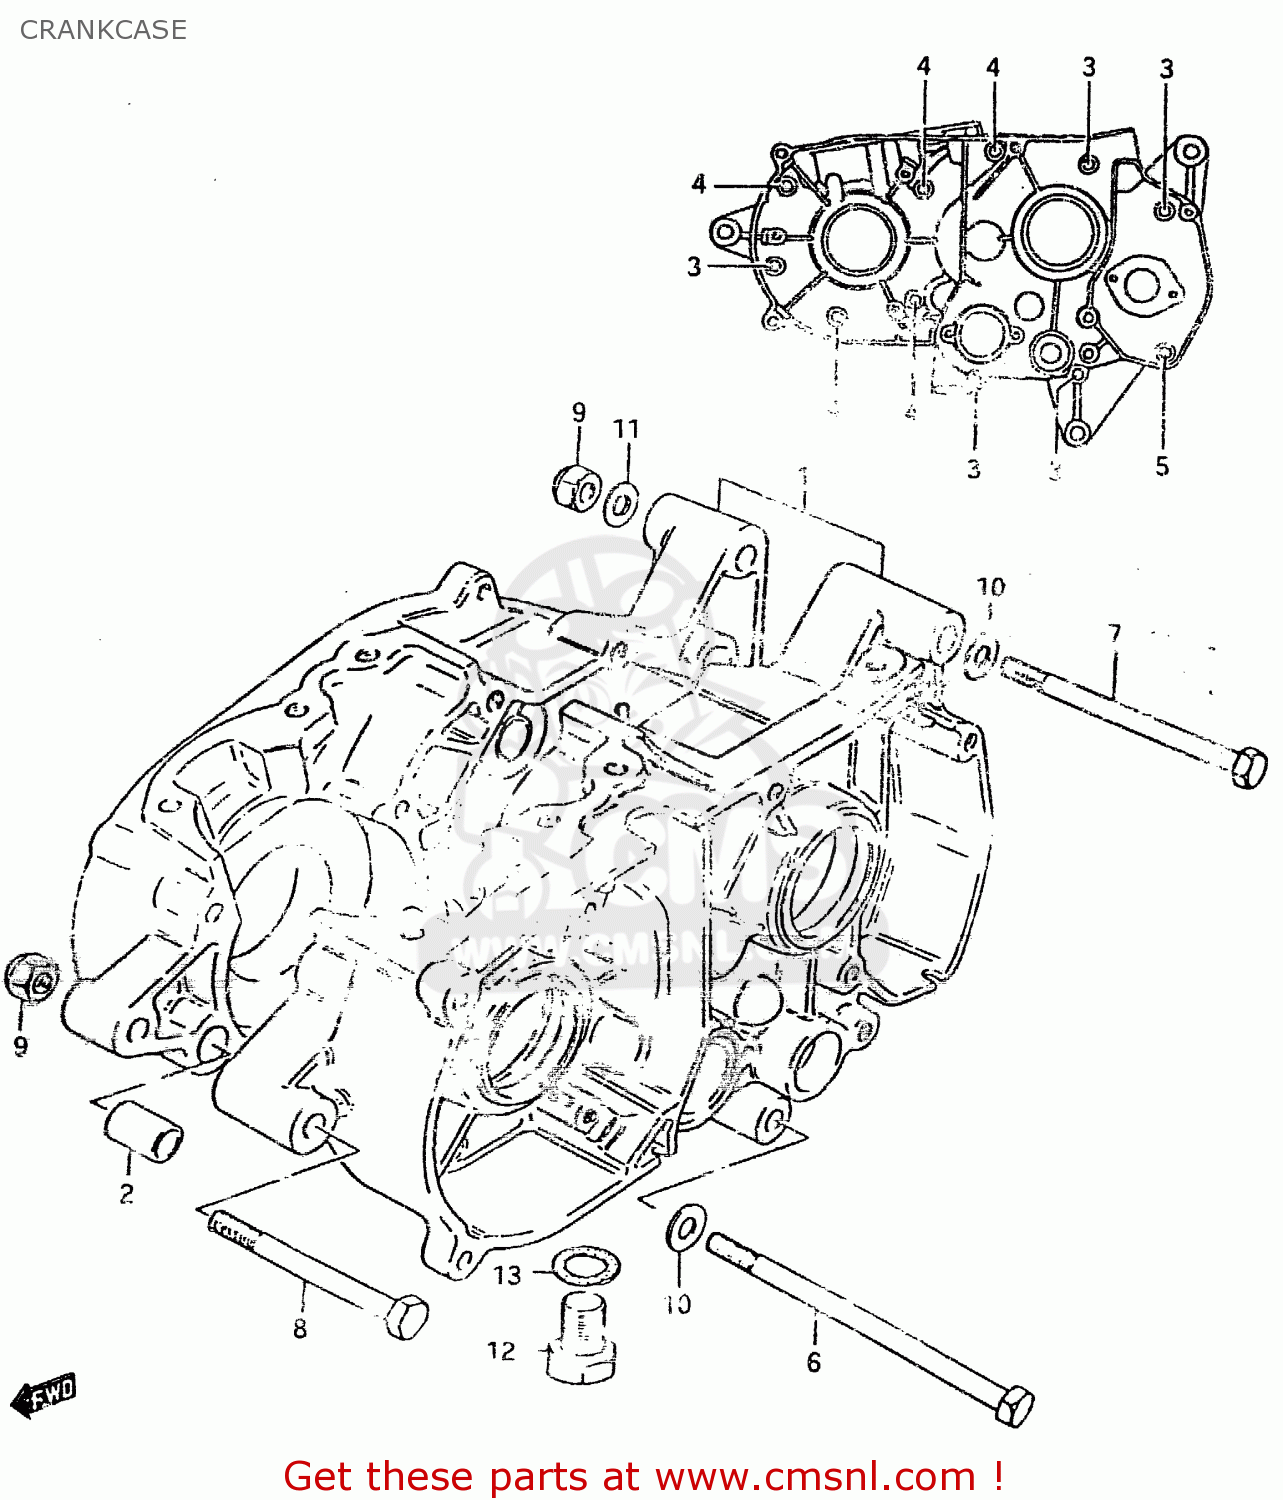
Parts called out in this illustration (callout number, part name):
1	CRANKCASE SET
2	PIN
3	SCREW (6X45)
4	SCREW (6X35)
5	SCREW
6	BOLT
7	BOLT
8	BOLT 8X75
9	NUT
10	WASHER
11	WASHER
12	BOLT 10X20
13	GASKET(10X14X3.6) (NAS)
